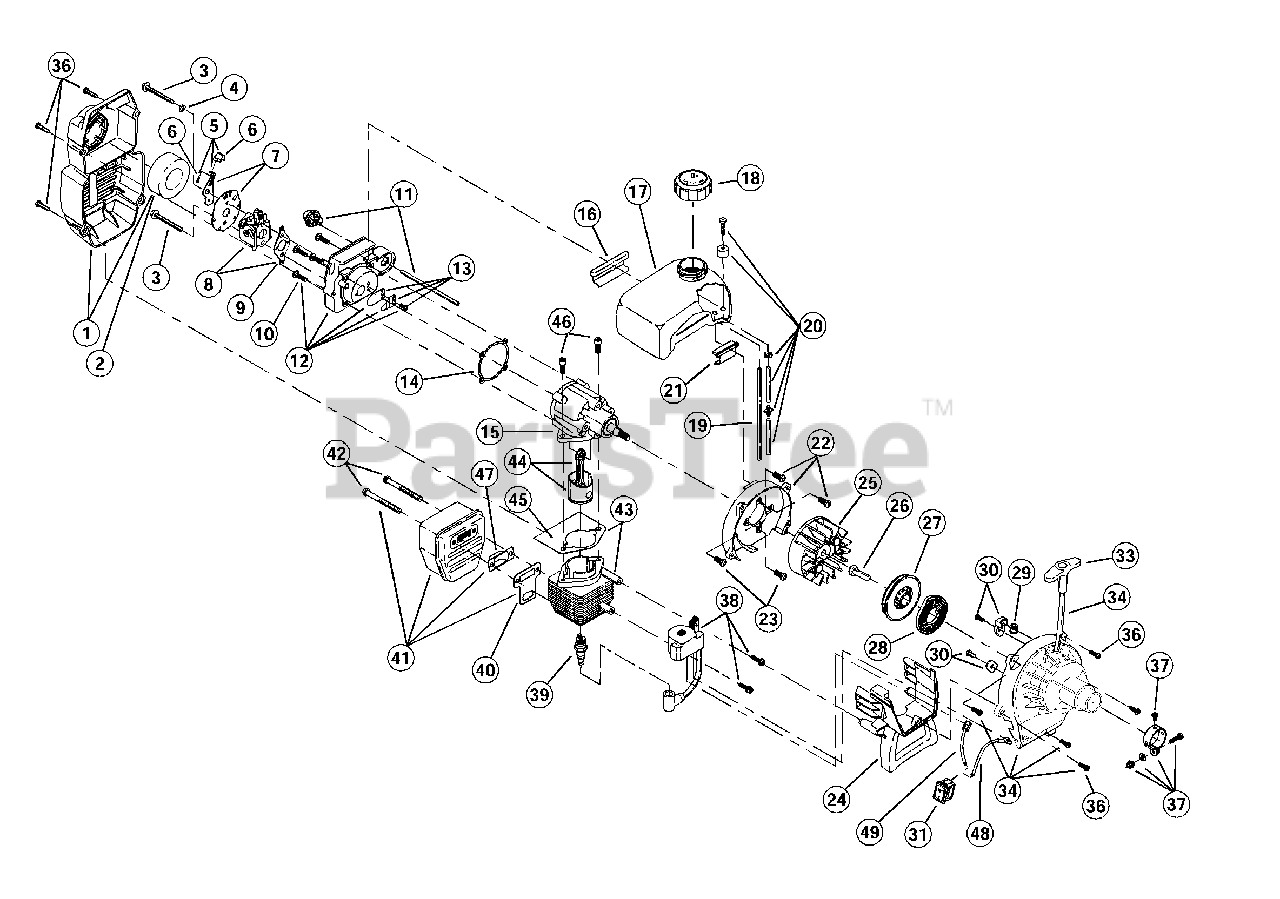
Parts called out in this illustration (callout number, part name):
1	Air Cleaner/Muffler Cover Assembly
2	Air Cleaner Filter
3	Carburetor Mounting Screw Assembly
4	Wavey Washer
5	Choke Lever Assembly
6	Choke Knob and Screw
7	Choke Lever and Plate
8	Carburetor Assembly W/Limiter Caps
9	Carburetor Gasket
10	Carb Mount Screw
11	Primer and Hose Assembly
12	Carb Mount Assembly
13	Reed Assembly
14	Carburetor Mount Gasket
15	Crank Case Service Assembly
16	Rear Mounting Pad
17	Fuel Tank Assembly
18	Fuel Cap Assembly
19	Fuel Return Line
20	Fuel Line Assembly
21	Front Mounting Pad
22	Shroud Assembly
23	Shroud Screw
24	Shroud Extension and Stand
25	Flywheel Assembly
27	Recoil Pulley Assembly
28	Recoil Spring
29	Rope Guide
30	Pulley Retainer Assembly
31	Momentary Switch
32	Pull Handle
34	Starter Housing Assembly
35	Housing Screw
36	Cover Screw
37	Upper Clamp Assembly
38	Governed Module Assembly
39	Spark Plug
40	Exhaust Gasket
41	Muffler Assembly
42	Muffler Mounting Bolt Assembly
43	Cylinder Assembly
44	Piston and Rod Assembly
45	Cylinder Gasket
46	Cylinder Bolt
47	Spark Arrestor
48	Lead Wires
